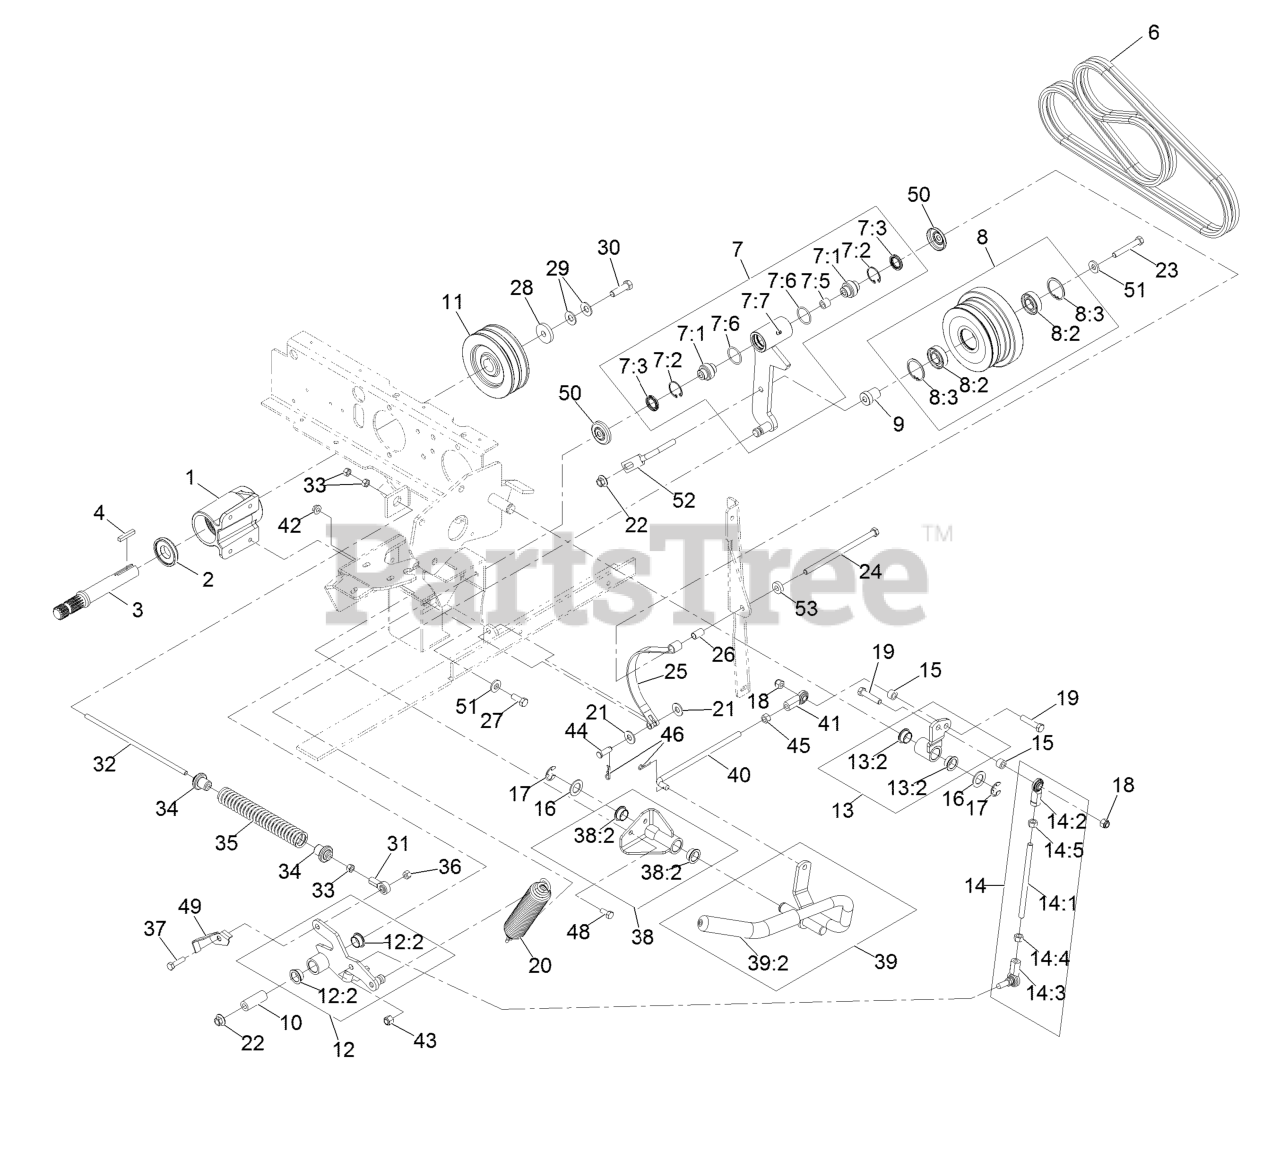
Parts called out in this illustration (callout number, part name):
1	Jackshaft ASM
2	Spacer-Guard, Bottom
3	Jackshaft
4	Key-Square
6	Belt, Matched Pair
7	Idler Pivot ASM
7:1	Bearing-Spherical
7:2	Ring-Snap
7:3	Seal-Lip, Single
7:5	Bushing-Lever, Lift
7:7	Fitting-Grease
8	Idler Sheave ASM
8:2	Bearing-Ball
8:3	Ring-Retaining
9	Spacer-Idler
10	Bushing
12	Arm ASM
12:2	Bushing-Bronze
13	Arm ASM
13:2	Bushing-Bronze
14	Clutch Link ASM
14:1	Rod-Linkage
14:2	Joint-Ball End, LH
14:3	Balljoint-RH
14:4	Nut-Hex
14:5	Nut-Hex, LH
18	Nut-Lock, NI
19	Screw-HH
20	Spring-Extension
21	Washer-Flat
23	Screw-HH
24	Screw-HH
25	Band-Brake
27	Screw-HH
28	Washer-Clutch
29	Washer-Spring
30	Screw-HH
31	Balljoint-RH
32	Linkage-Rod, PTO Brake
33	Nut-Hex
34	Bushing-Spring
35	Spring-Brake
36	Nut-Lock, NI
37	Screw-HH
38	Pivot ASM
38:2	Bushing-Bronze
39	PTO Handle ASM
39:2	Grip-Lever, Control
40	Link-Handle
41	Joint-Ball, End
43	Nut-Lock
44	Pin-Clevis
45	Nut-Hex
46	Pin-Cotter
48	Screw-HH
49	Switch-Flag
50	Guard-Top
51	Washer-Belleville
52	Guide-Belt
53	Spacer
